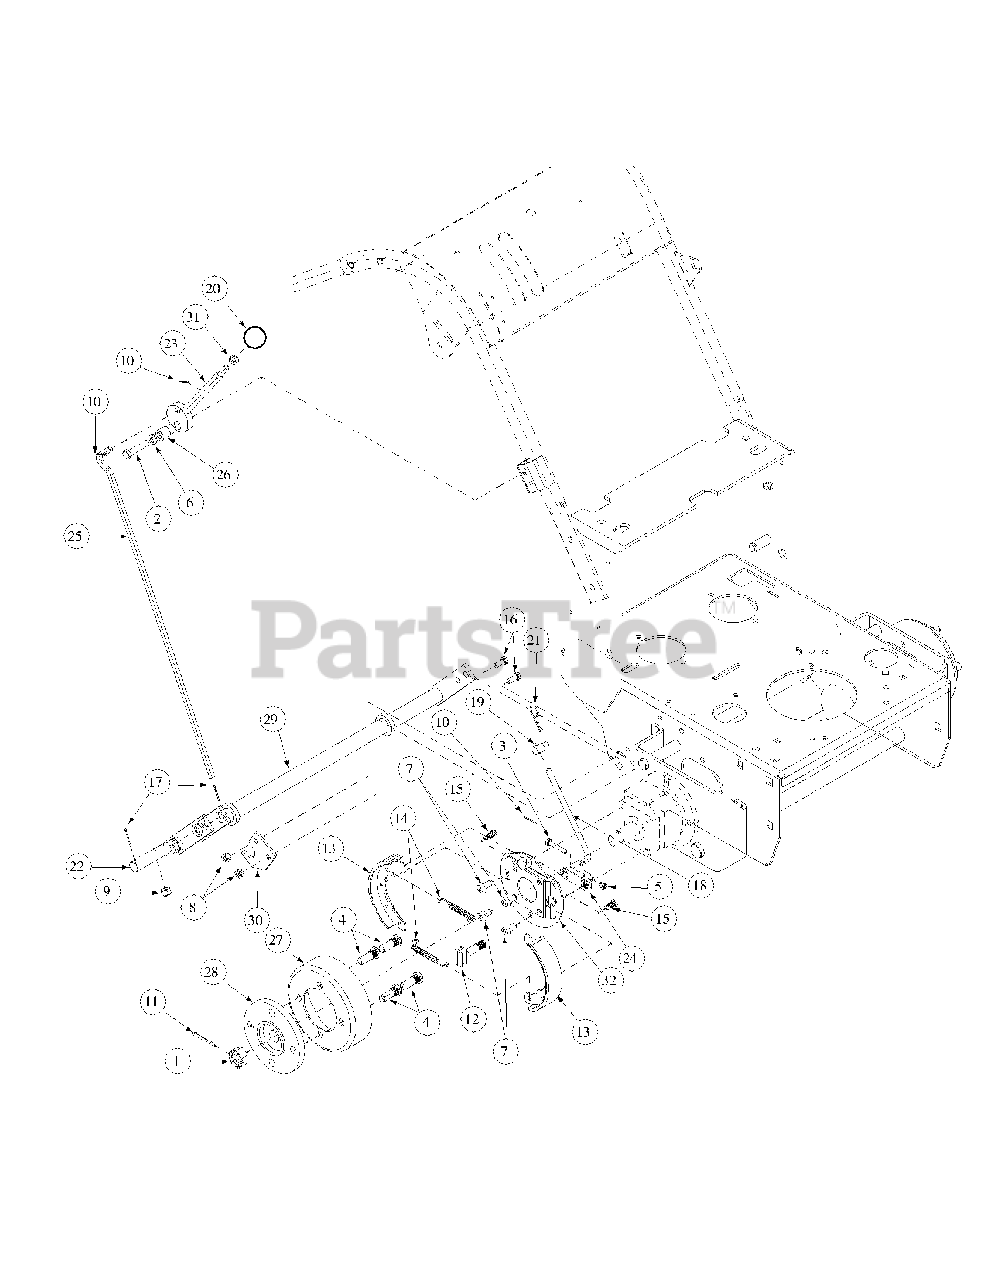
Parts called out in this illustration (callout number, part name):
1	Nut, Castle, 3/4-16
2	Capscrew, 3/8-16 x 1" Grade 5 Zinc
3	Cap Screw, 1/4-20 x 1.50, Grade 5
4	Bolt, Wheel, 1/2-20 x 1-3/8
5	Lock Nut, Nylon Insert, 1/4-20 Grade A
6	Lock Washer, 3/8 Zinc
7	Capscrew, Socket Button Hd., 3/8-16 x 3/4 Zinc
8	Nut, 5/16-18, Nylock
9	Nut, Nylon Insert, 3/8-16 Grade A
10	Cotter Pin, 3/32 x 3/4, Zinc
11	Cotter Pin, 5/32 x 1-1/2 Zinc
12	Brake Cam, Actuating
13	Brake Shoe w/Lining, 6 x 1-1/4
14	Brake Spring, Tension
15	Brake Spring, Anti-Vibration
16	Cap Screw, 5/16-18 x 3/4, Grade 5
17	Cotter Pin, 3/32 x 1, Zinc
18	Brake Rod
19	Swivel Joint
20	Knob, Red, Shift w/Insert
21	Hair Pin, 3/8"-1/2"
22	Joint, Brake Pull
23	Lever Assembly, Brake
24	Brake Clamp, Control Assembly, Hydro
25	Rod, Long Brake, Hydro WB
26	Pivot Spacer, Hydro WB
27	Brake Drum
28	Hub, Wheel Motor
29	Brake Shaft Assembly WT
30	Pivot Mount, Brake
31	Nut, 3/8-16, Jam, Grade 2
32	Brake Backing Plate
